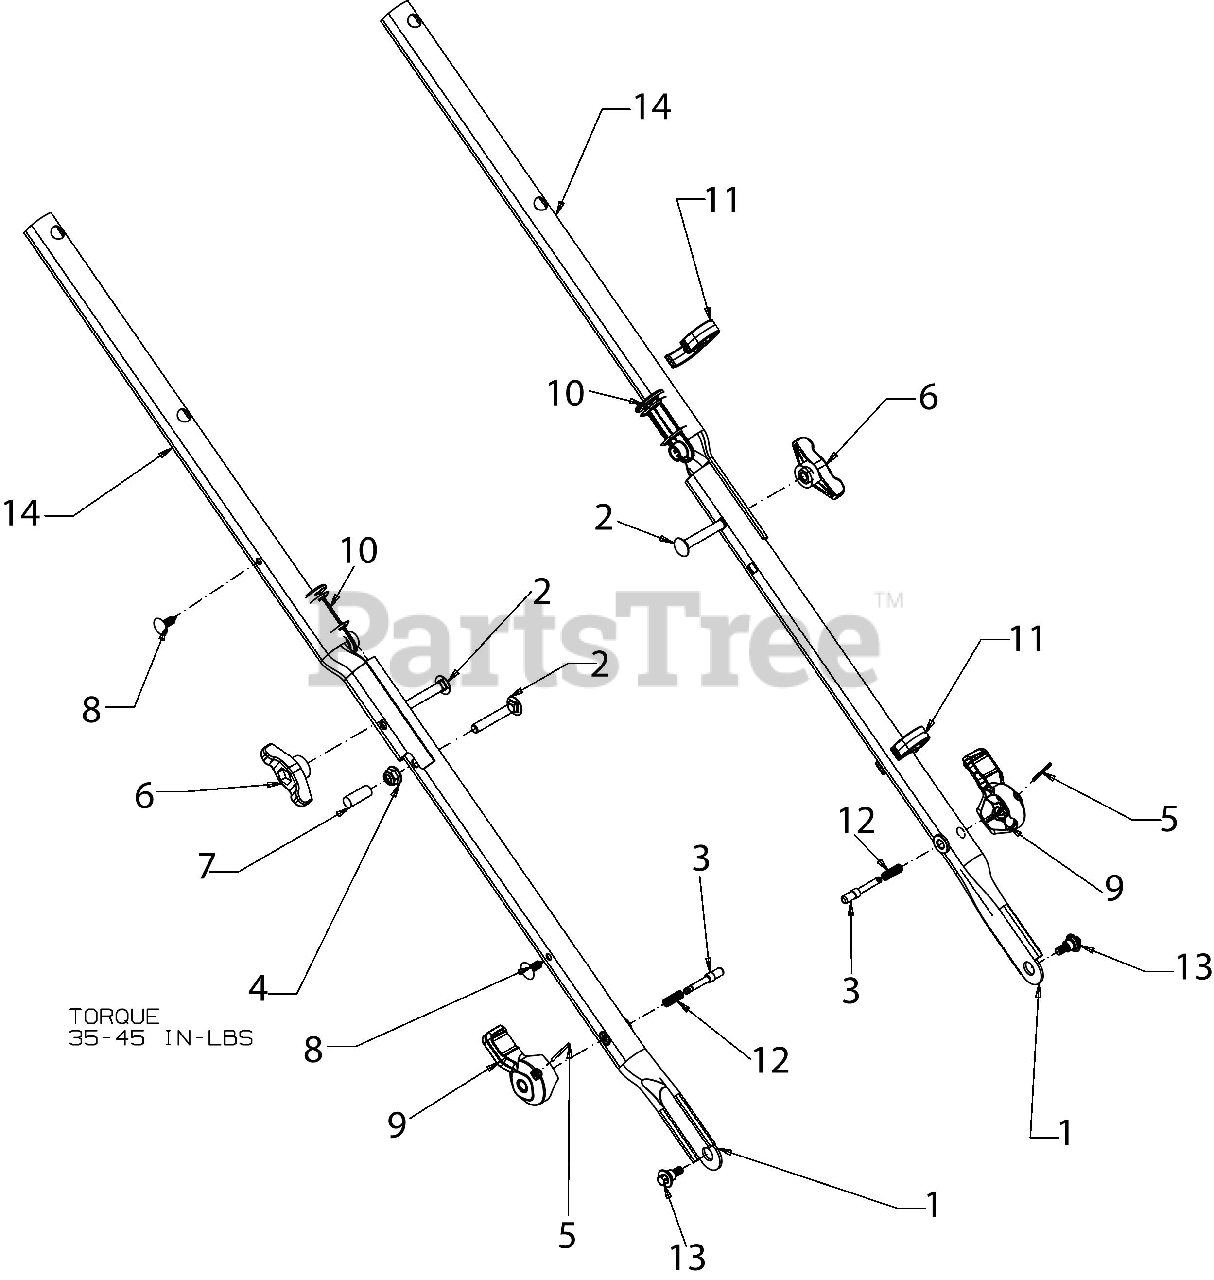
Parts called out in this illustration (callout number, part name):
1	LOWER HANDLE ASSEMBLY
2	BOLT 5/16-18 x 2.00 GR5
3	HANDLE ADJUSTMENT PIN
4	FLANGE LOCK NUT 5/16-18
5	SPLIT ROLL PIN 5/64 X 1.38
6	WING KNOB 5/16-18
8	RATCHET CLIP .250
9	HANDLE LEVER KNOB
10	HANDLE END PLUG
12	COMPRESSION SPRING
13	SHOULDER SCREW .500 X.118X1/4-20
14	UPPER HANDLE
